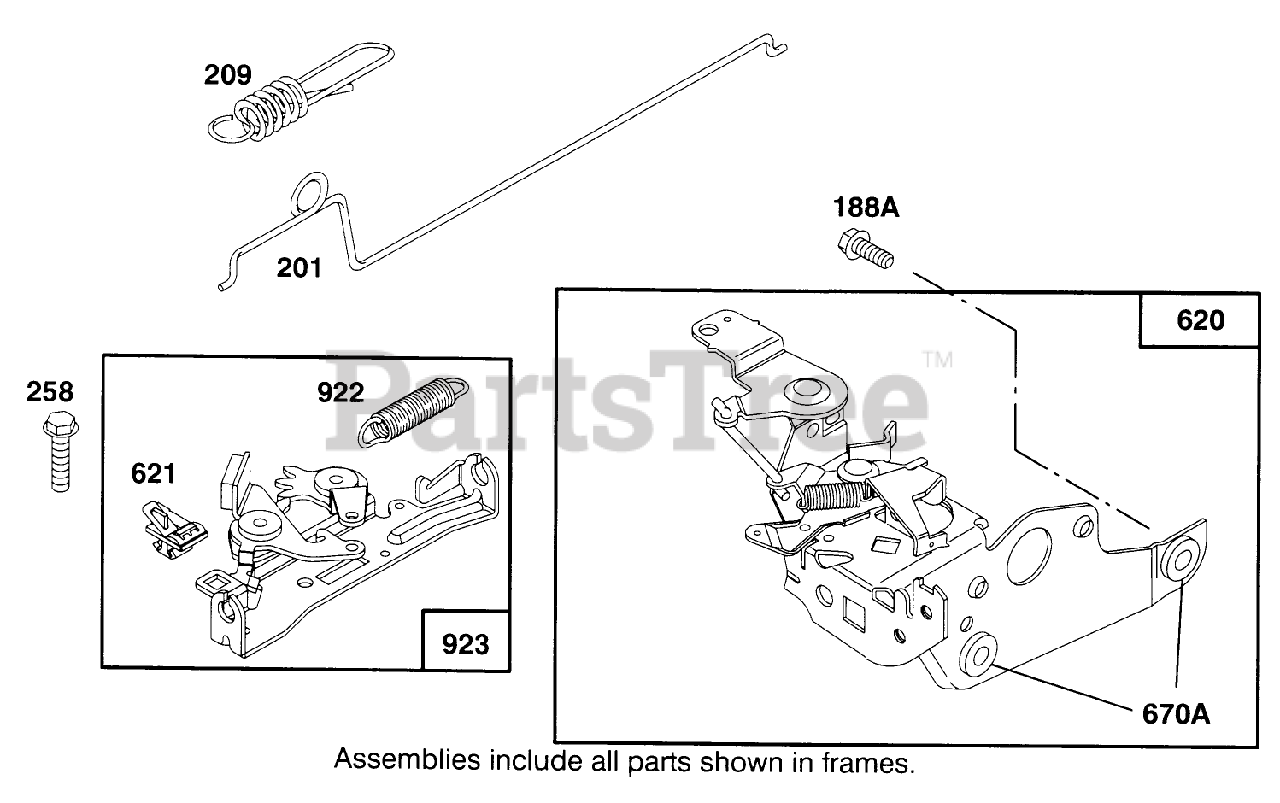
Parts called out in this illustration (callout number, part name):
188A	Screw-Hex.
201	Link-Govemor
209	Spring-Govemor
258	Screw-Sem
620	Bracket-Carburetor
621	Switch
670A	Spacer
922	Brake Spring
923	Brake
